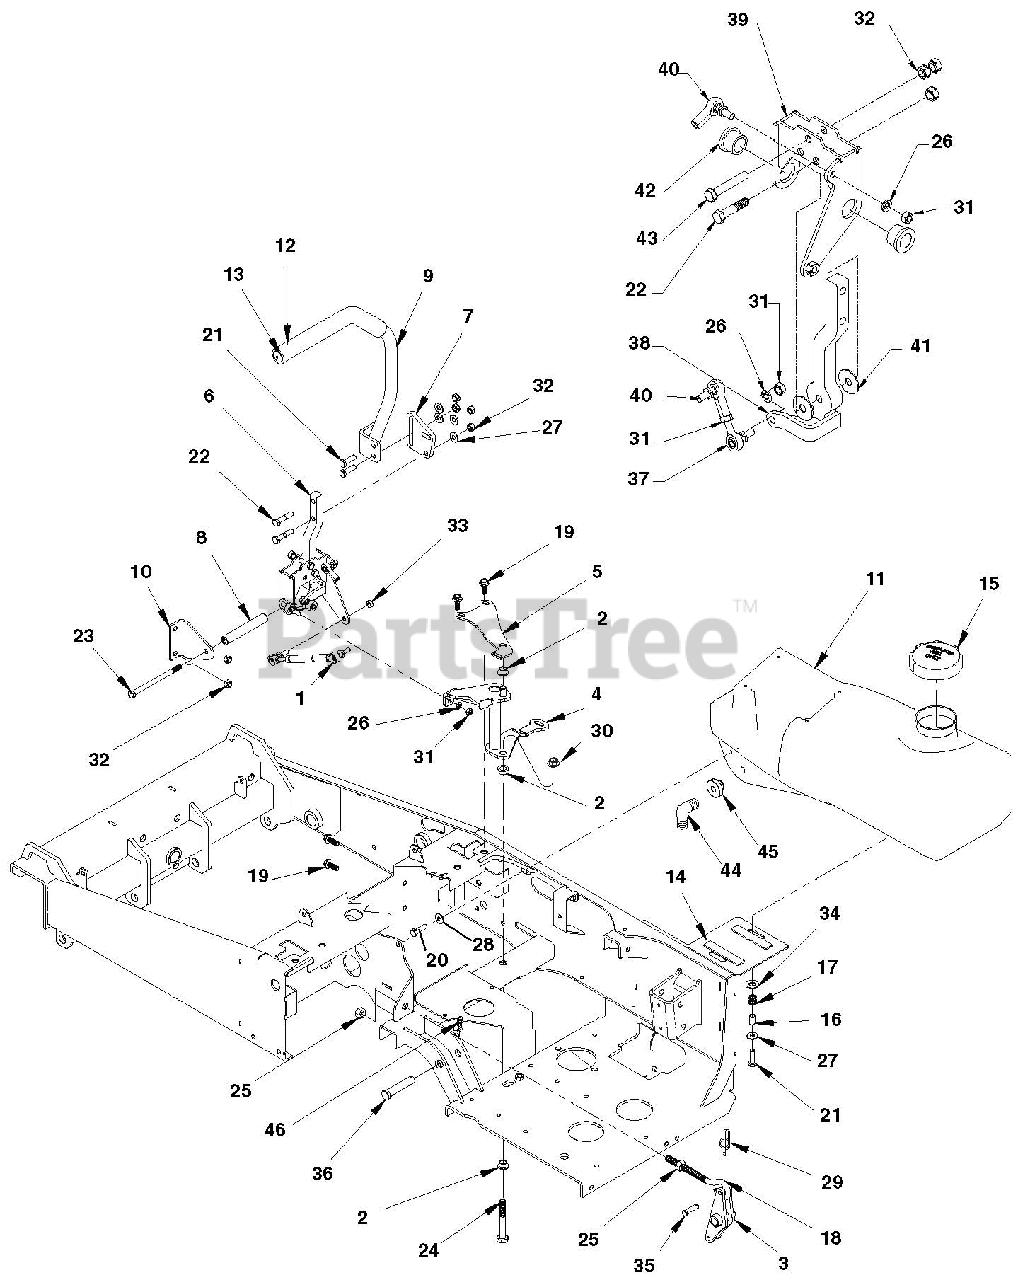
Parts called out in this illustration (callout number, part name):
1	DAMPNER, STEERING CONTROL
2	BRG, FLG .502X.629X.421
3	WLDT, SPRING PIVOT
4	WLDT, RH PARK BRAKE CONTROL
4	WLDT, LH PARK BRAKE CONTROL
5	EAR, RH BRAKE PIVOT
5	EAR, LH BRAKE PIVOT
6	WLDT, RH STEERING BAR
6	WLDT, LH STEERING BAR
7	PLATE, HANDLE HEIGHT
8	TUBE, RD .750 X .179 X 4.69 Y
9	ASSY, RH STEERING HANDLE
9	ASSY, LH STEERING HANDLE
10	PLATE, BENT
11	TANK, RH MIDMOUNT BLANK W/CAP
11	TANK, LH MIDMOUNT BLANK W/CAP
12	FOAM GRIP
13	PLUG, 7/8" END
14	FOAM, .125 X .750 X 4.00
15	CAP, FUEL S/O
16	SPACER, GAS TANK ATTACHMENT
17	SPRING, COM .660 X .067 X .625
18	EYEBOLT, 1/2-13X1.00X4.50 FL Y
19	BOLT, 3/8-16X1.00 FGH 8 Y
20	BOLT, 3/8-16X.750 HEX 5 Y
21	BOLT, 3/8-16X1.25 HEX 5 Y
22	BOLT, 3/8-16X1.75 HEX 5 Y
23	BOLT, 3/8-16X5.50 HEX 5 Y
24	BOLT, 1/2-13X2.75 HEX 5 Y
25	NUT, 1/2-13 STD HEX GR5 Y
26	WASHER, .313 MED SPRG LOCK Y
27	WASHER, .313 REG FLAT Y
28	WASHER, .375 REG FLAT Y
29	RING, RUE .375 X .054 X 1.254
30	LOCKNUT, 1/2-13 CROWN Y
31	NUT, 5/16-24 STD HEX GR5 Y
32	LOCKNUT, 3/8-16 CROWN Y
33	LOCKNUT, M8-1.25 CROWN Y
34	WASHER, .500X1.00X.105 FLAT Y
35	PIN, CVS .375X1.38X1.14 Y
36	PIN, CVS .625X3.00X2.77 Y
37	BALL JOINT, RH 5/16 MALE W/STD
38	WLDT, RH STEERING BAR
38	WLDT, LH STEERING BAR
39	WLDT, HANDLE CONTROL RH
39	WLDT, HANDLE CONTROL LH
40	BALL JOINT, RH 5/16 FMAL W/STD
41	WASHER, .400X1.27X.062 NYLON
42	BUSHING, .750 X 1.00 X .750
43	BOLT, 3/8-16X2.25 HEX 5 Y
44	FTG, 90 1/4HOSE X 1/2HOSE S/O
45	GROMMET, RUBBER TANK S/O
46	RING, RUE .625 X .072 X 1.690
